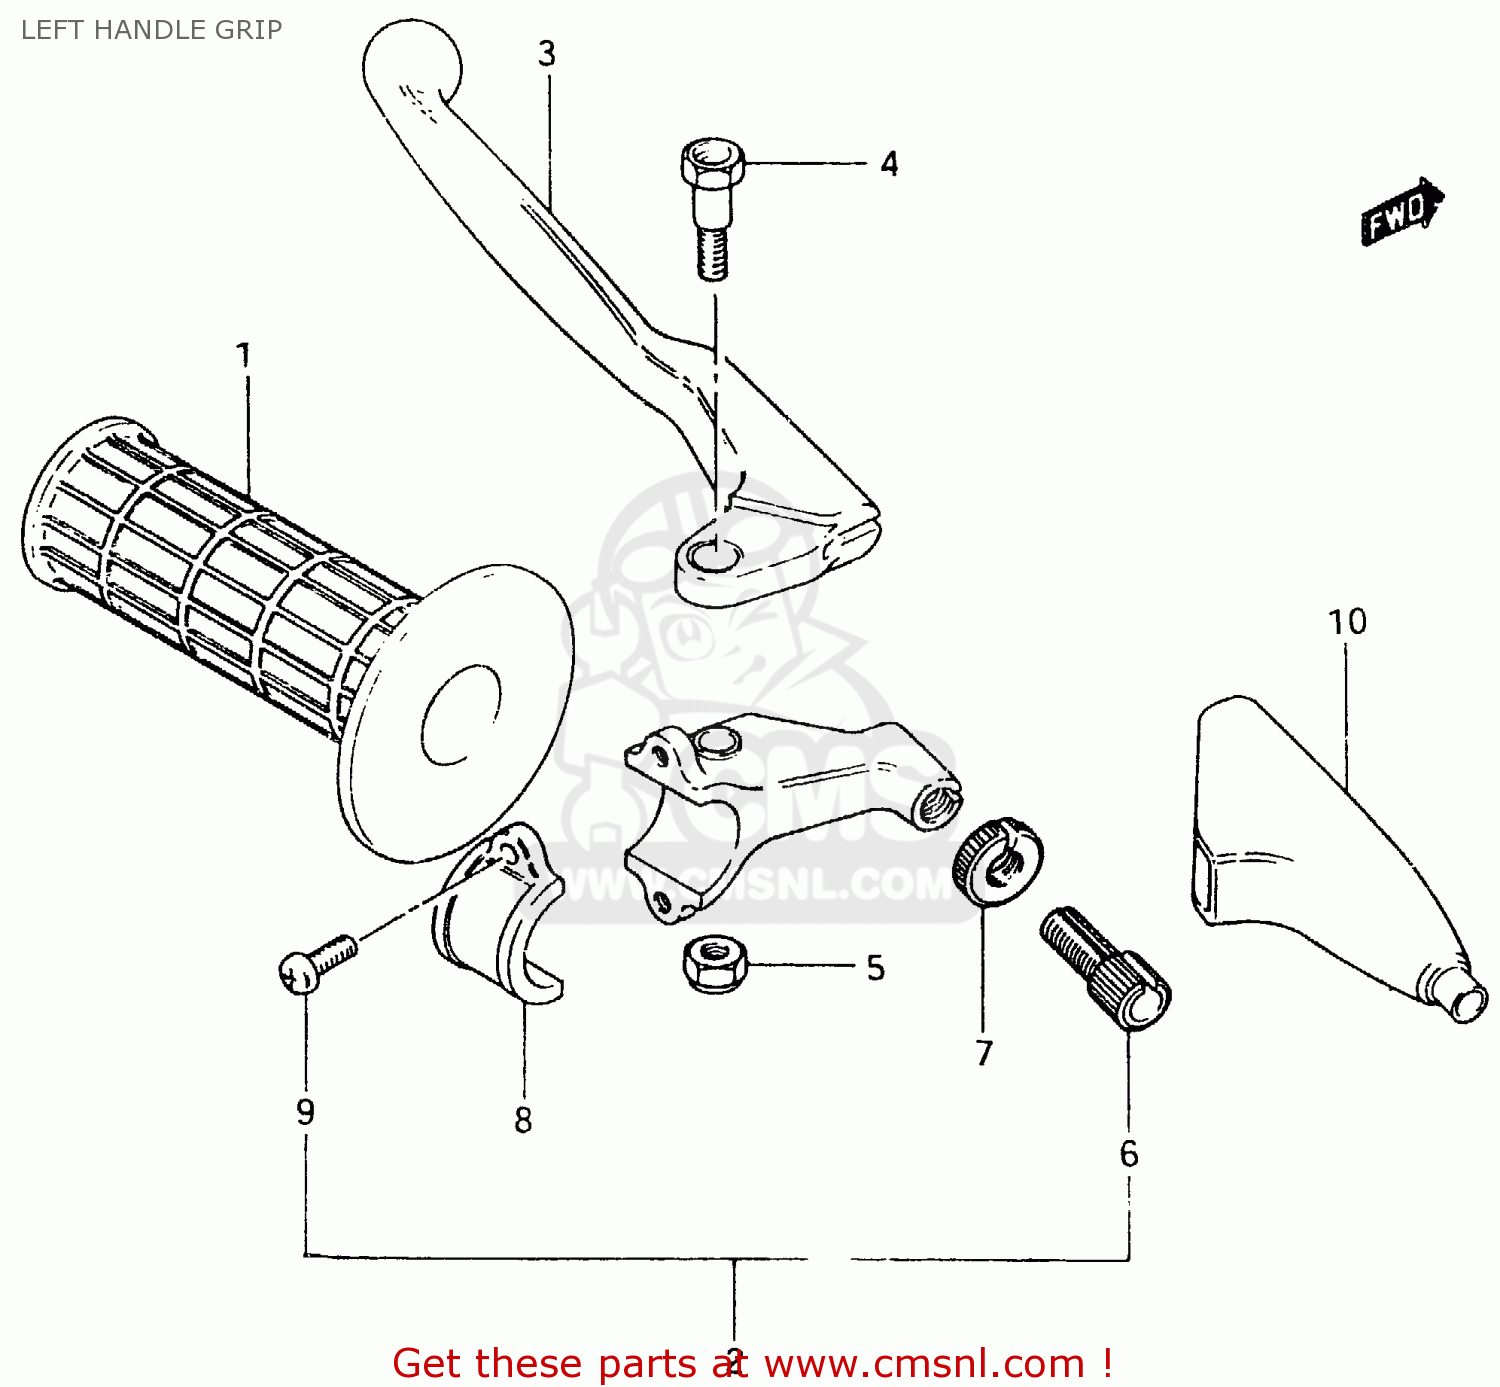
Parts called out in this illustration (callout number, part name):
1	GRIP,LEFT
2	LEVER ASSY,CLUTCH
3	LEVER,CLUTCH
4	BOLT,LEVER
5	NUT 6MM
6	ADJUSTER,CABLE
7	NUT,CABLE ADJUSTER
8	BRACKET,CLUTCH LEVER HOLDER
9	SCREW
10	COVER,CLUTCH LEVER
